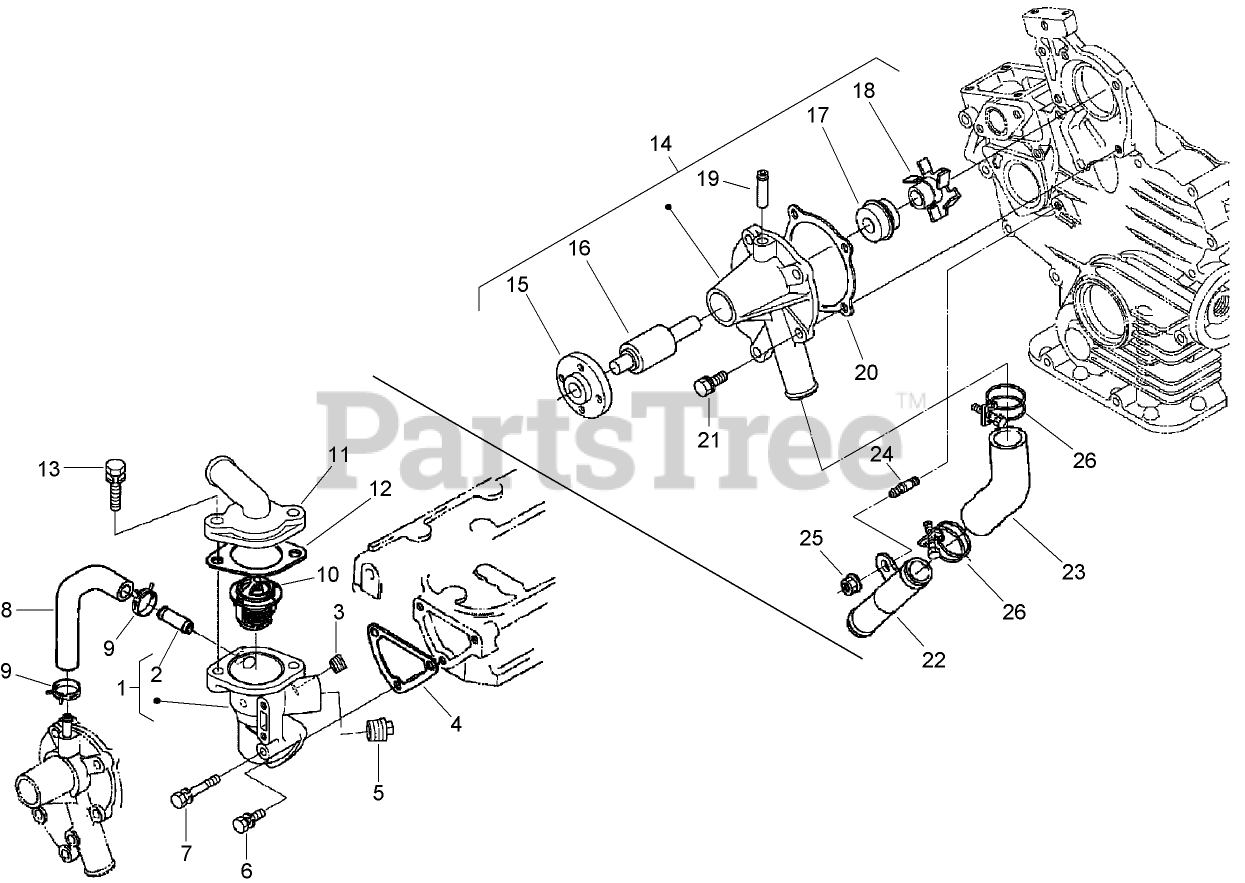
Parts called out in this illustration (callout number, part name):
1	WATER FLANGE ASM
2	PIPE-RETURN, WATER
4	GASKET-FLANGE, WATER
7	BOLT
8	PIPE-RETURN, WATER
9	BAND-PIPE
10	THERMOSTAT ASM
11	COVER-THERMOSTAT
12	GASKET
14	WATER PUMP ASM
15	FLANGE-PUMP, WATER
16	BEARING-BALL
17	WATER PUMP SEAL ASM
18	IMPELLER-PUMP, WATER
19	PIPE-RETURN, WATER
20	GASKET-PUMP, WATER
22	PIPE-WATER
23	PIPE-WATER
25	NUT-FLANGE
26	BAND-PIPE
